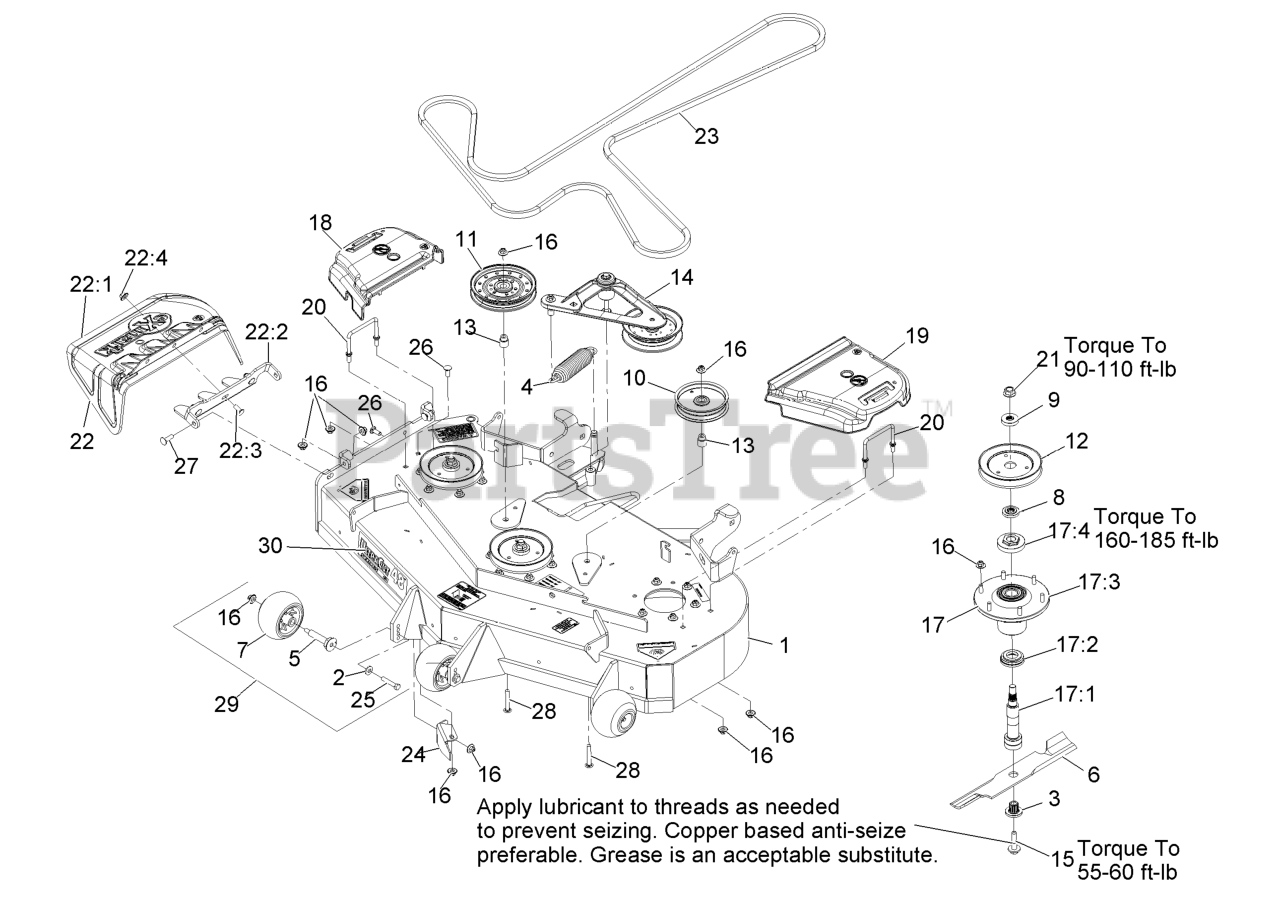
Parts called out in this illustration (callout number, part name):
1	ASM,DECK W/DECALS 48
2	WASHER-BELLEVILLE
3	BUSHING,SPLINED
7	ROLLER-SCALP, ANTI
8	SPACER,SPLINED STEPPED
9	SPACER,SPLINED
10	PULLEY-IDLER
12	SHEAVE,BLADE DRIVE 5.90
13	BUSHING-IDLER
14	DECK IDLER ASM
15	SCREW,SEMS 1/2-20 X 2.19
16	Nut-Nyloc 3/8-16 Flg
17	ASM,SPINDLE HOUSING
17:1	GUARD,BOTTOM
17:2	ASM,CUTTER HOUSING
17:3	NUT, SPINDLE 7/8-14
17:4	SPINDLE,DOUBLE SPLINE
18	COVER-BELT, RH
19	COVER-BELT, LH
20	WIREFORM-COVER
21	NUT-FLANGE, CENTERLOCK
22	ASM,DISCHARGE CHUTE
22:1	CHUTE,DISCHARGE
22:2	BRACKET,DISCHARGE CHUTE
22:3	SCREW-CARR
22:4	Nut-Nyloc 3/8-16 Flg
23	BELT
24	BAFFLE,DISCHARGE
25	SCREW-HH
26	SCREW-CARR
27	Bolt-Carriage 3/8-16 X 1 1/4
28	SCREW-CARR
30	DECAL,ULTRACUT 48 SERIES
